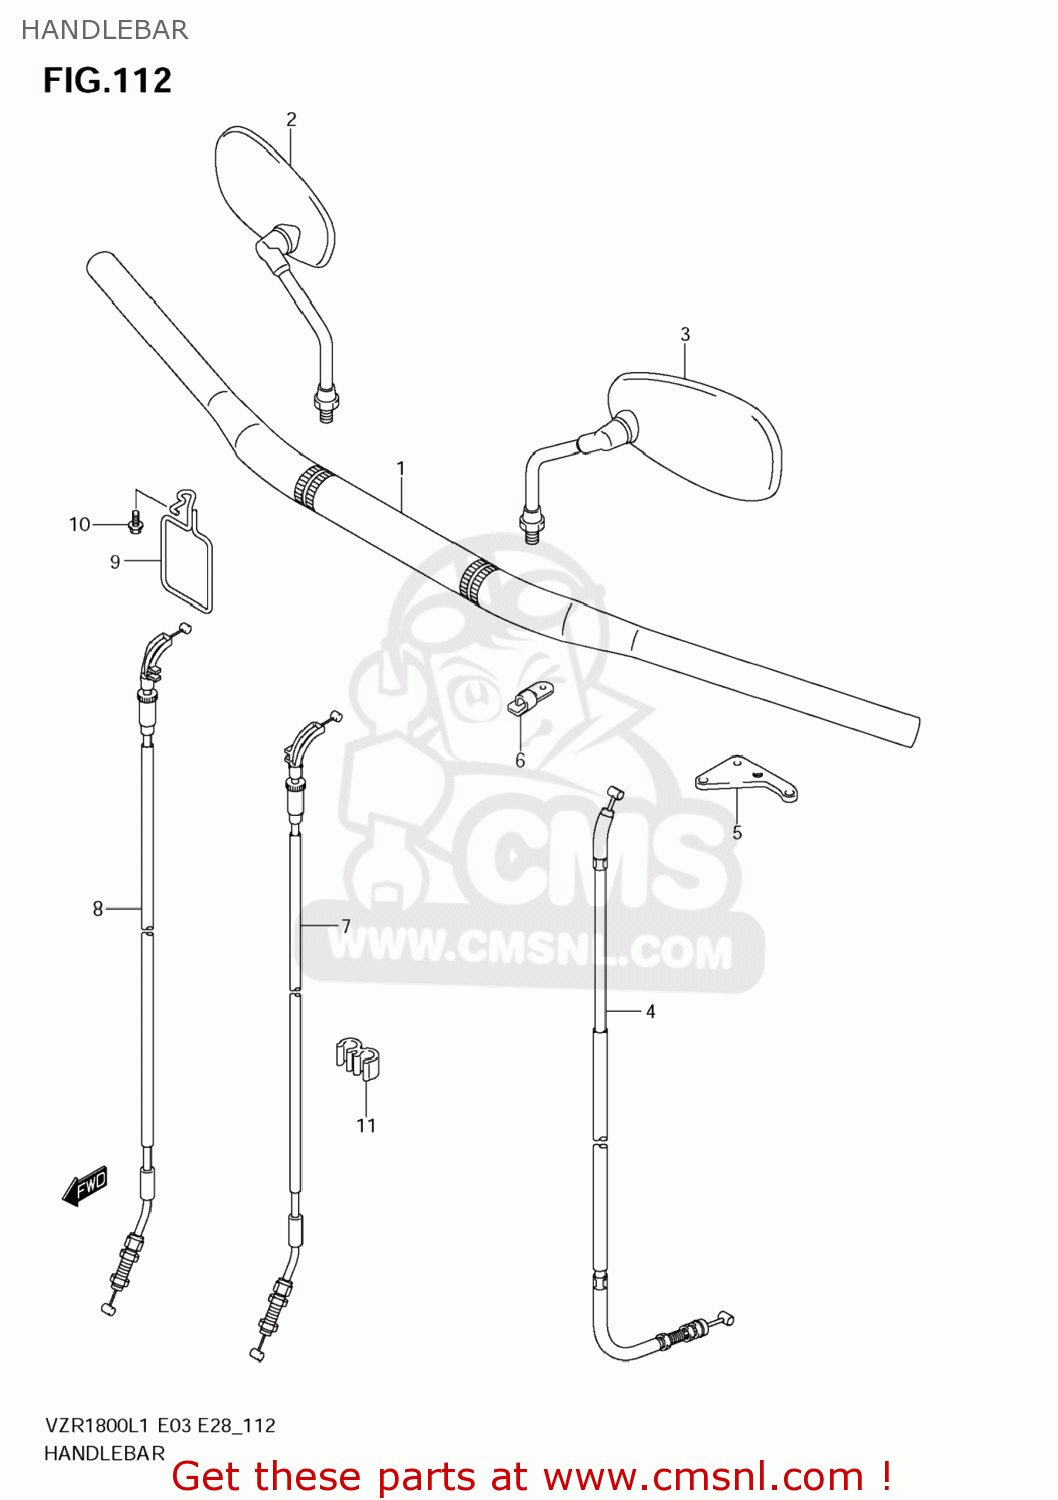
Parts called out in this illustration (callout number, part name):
1	HANDLEBAR
2	MIRROR ASSY,RR VIEW,R
3	MIRROR ASSY,RR VIEW,L
4	CABLE ASSY,CLUTCH
5	STOPPER,CLUTCH CABLE NO.1
6	STOPPER,CLUTCH CABLE
7	CABLE ASSY,THROTTLE NO.1
8	CABLE ASSY,THROTTLE NO.2
9	GUIDE,CABLE NO.2
10	BOLT
11	CLIP
